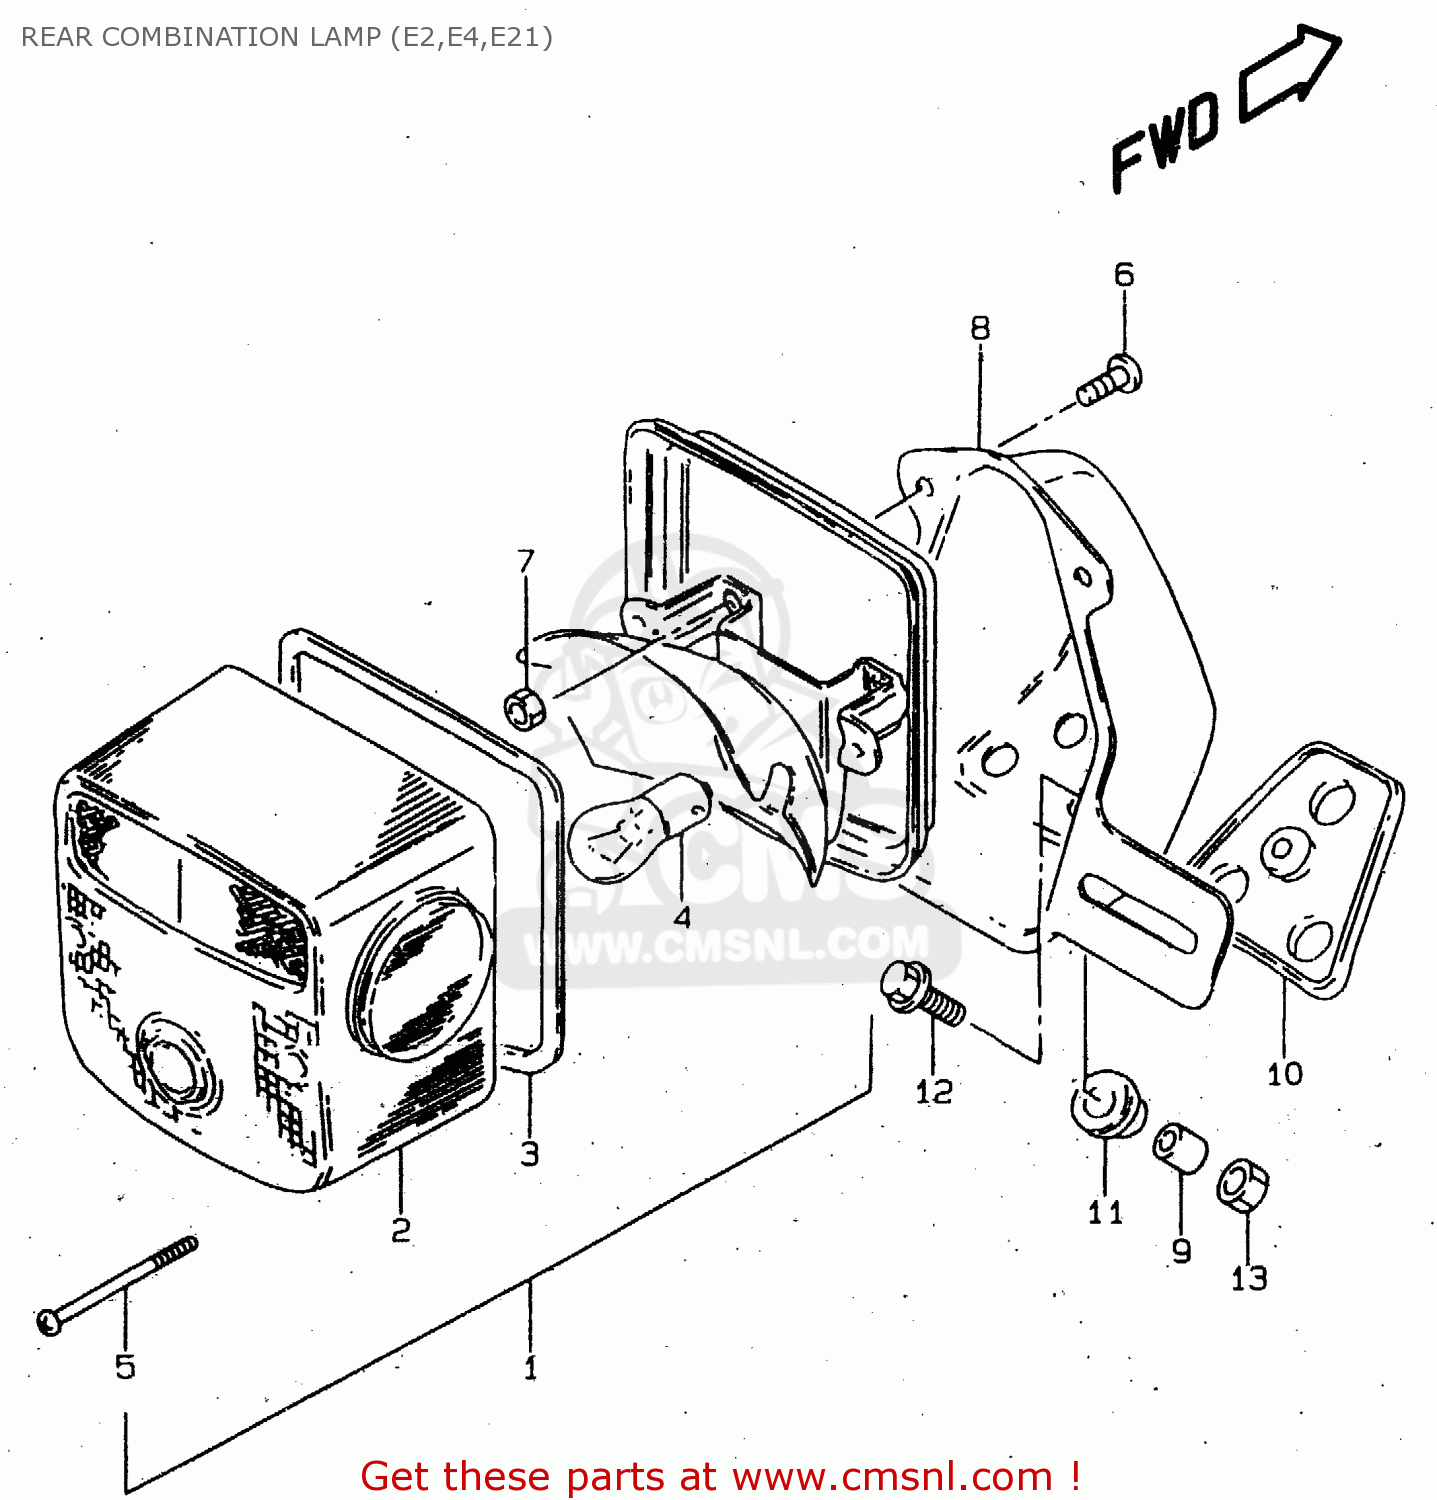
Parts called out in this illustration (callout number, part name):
1	LAMP UNIT,RR COMBNATION
2	LENS
3	GASKET (NAS)
4	BULB(12V21/5W)
5	SCREW (4X55)
6	SCREW
7	NUT
8	BRACKET UNIT,TAIL LAMP
9	SPACER
10	CUSHION
11	CUSHION
12	BOLT(6X20)
13	NUT 6MM
